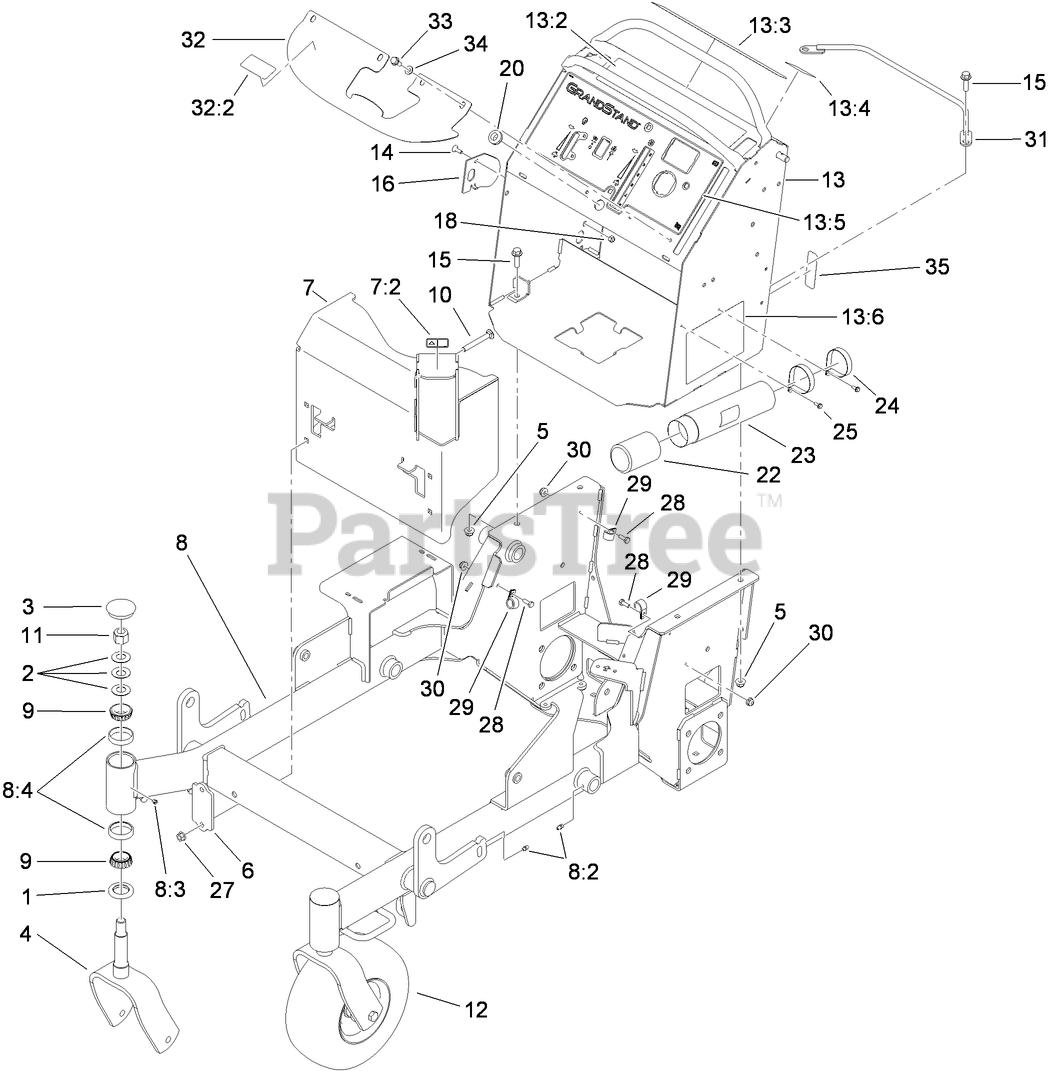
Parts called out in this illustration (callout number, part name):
1	SEAL-GREASE
2	WASHER-BELLVILLE
3	CAP-GREASE
4	FORK-CASTER
5	NUT-HF, NI
6	BRACKET-MOUNTING, GUARD
7	MUFFLER GUARD ASM
7:2	DECAL-WARNING
8	FRAME ASM
8:2	FITTING-GREASE
8:4	CUP-BEARING
9	BEARING-ROLLER, TAPERED
10	SCREW-CARR
11	NUT-LOCK, NI
12	WHEEL/TIRE AND BEARING ASM
13	CONTROL TOWER ASM
13:2	DECAL-OPC
13:3	DECAL-WARNING
13:4	DECAL-STABILITY
13:5	DECAL-PANEL, CONTROL
13:6	DECAL-SERVICE AID
14	BOLT-CARR
15	SCREW-HHF
16	PLATE-STRIKER
18	NUT-LOCK, NI
20	GROMMET
22	CAP-HOUSING
23	TUBE-MANUAL
24	CLAMP-R
25	SCREW-TAPTITE
27	NUT-HF
28	SCREW-HH
29	CLAMP-CABLE
30	NUT-HF
31	RETAINER-CABLE
32	COVER-TANK
32:2	DECAL-FILL, FUEL
33	SCREW-HWHTF
34	WASHER-FLAT
35	DECAL-FUSE
